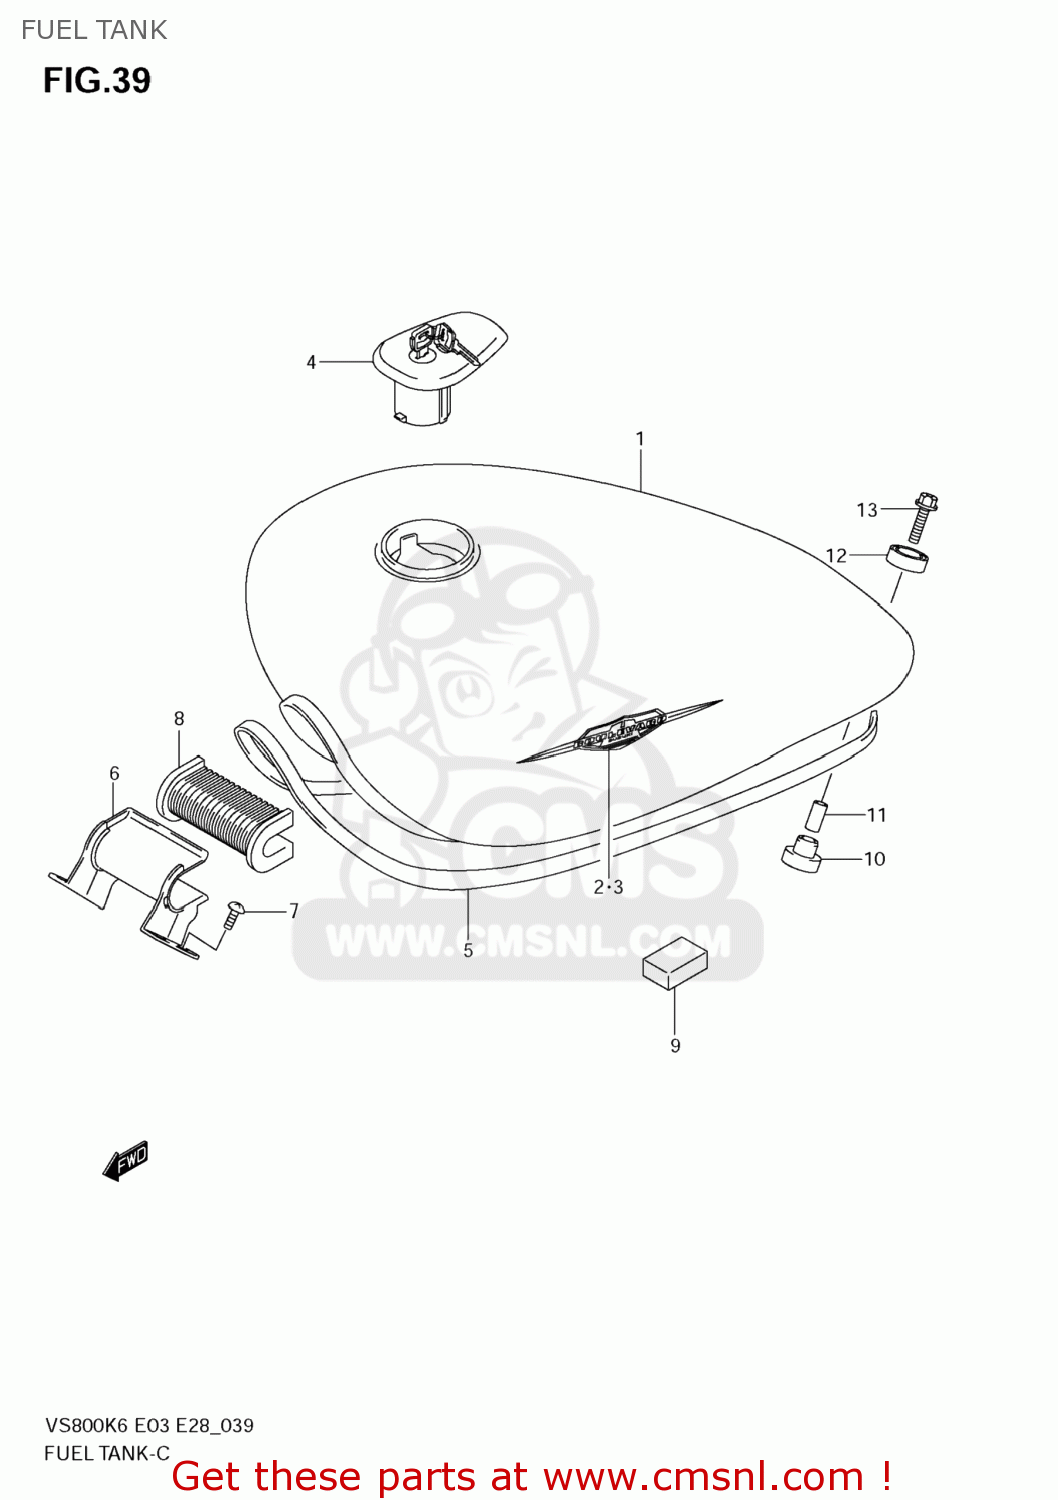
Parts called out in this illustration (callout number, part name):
1	TANK ASSY,FUEL(SILVER)
2	EMBLEM,FUEL TANK,R
3	EMBLEM,FUEL TANK,L
4	CAP SET,FUEL TANK
5	MOLDING
6	BRACKET,FUEL TANK FR
7	SCREW
8	CUSHION,FUEL TANK FR
9	CUSHION
10	CUSHION
11	SPACER(6.5X9X21.5)
12	CUSHION
13	SCREW(6X35)
